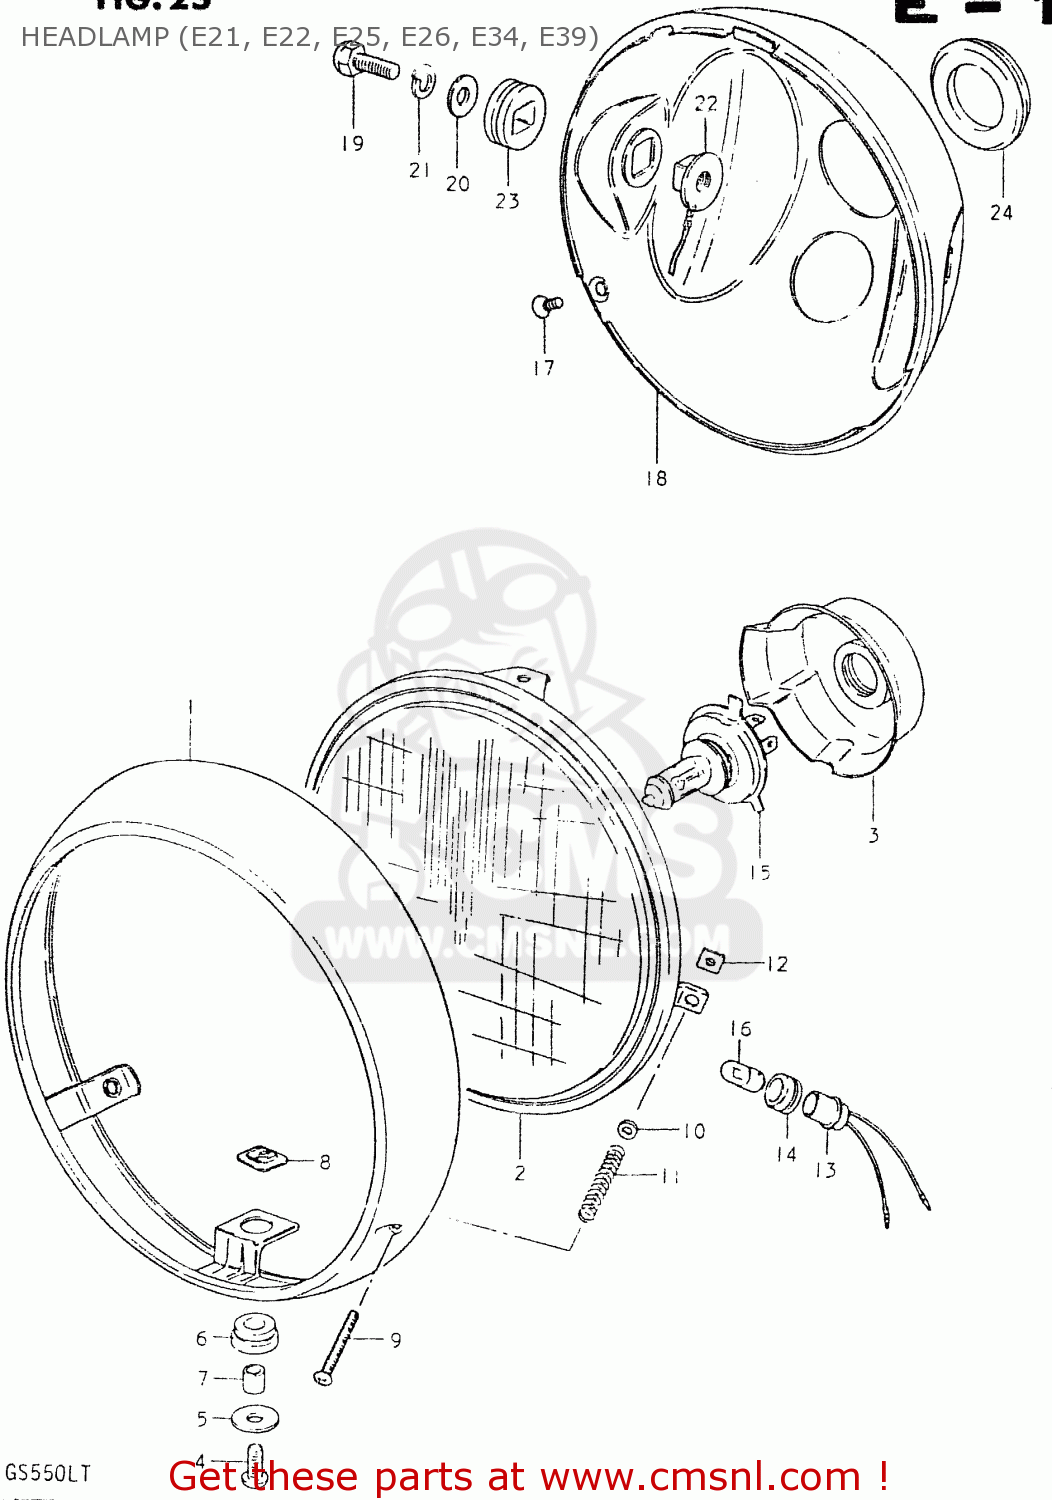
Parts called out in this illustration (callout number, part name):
1	RIM
2	LAMP UNIT
3	COVER,HEADLAMP SOCKET
4	SCREW
5	WASHER
6	CUSHION
7	SPACER
8	NUT
9	SCREW,HEADLAMP ADJUST
10	WASHER
11	SPRING,HEADLAMP ADJUST
12	NUT,HEADLAMP ADJUSTER
13	SOCKET
14	JOINT,RUBBER
15	BULB(12V60/55W,H4)
16	BULB
17	SCREW
18	HOUSING,HEADLAMP
19	BOLT
20	WASHER
21	LOCK WASHER
22	SPACER,HEADLAMP HOUSING
23	CUSHION,HEADLAMP HOUSING
24	GROMMET,HEADLAMP HOUSING
